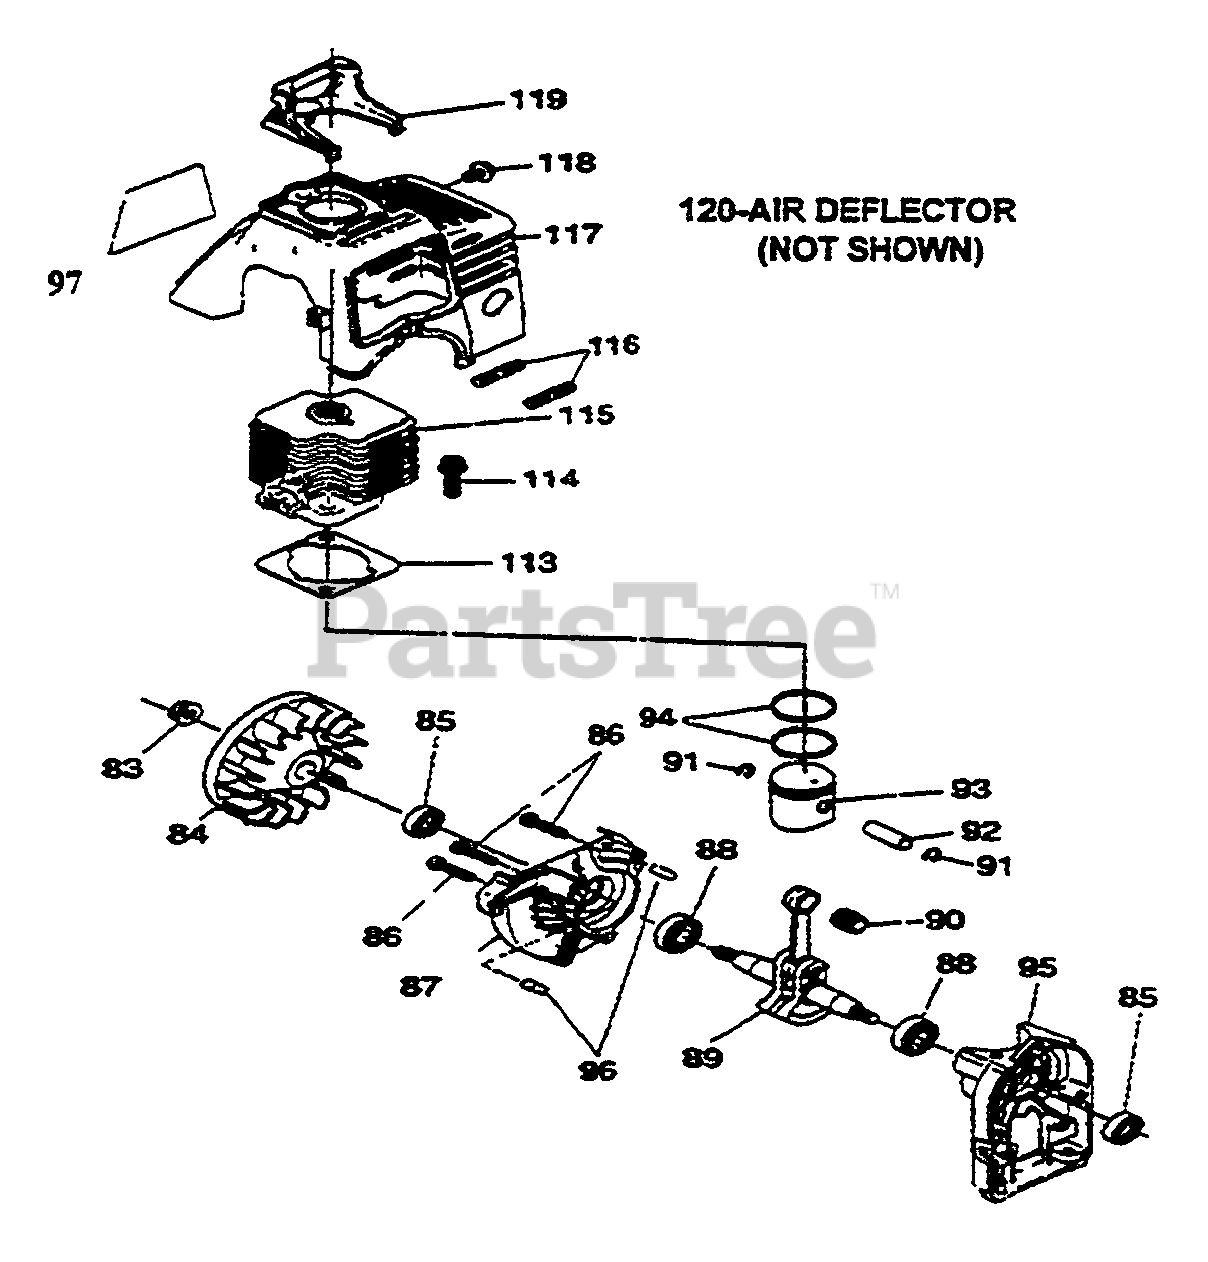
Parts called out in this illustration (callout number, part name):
83	NUT, CONICAL SPG.
85	OIL SEAL
87	CASE, DRIVE
88	BEARING, BALL
89	CRANKSHAFT ASSY
90	BEARING, NEEDLE
91	CLIP, PISTON PIN
92	PIN, PISTON
94	RING, TOP
95	CASE, STARTER
96	DOWEL PIN
97	DECAL
113	GASKET, CYLINDER
114	BOLT, FLANGE
116	BOLT, STUD
117	COVER, TOP
118	SCREW & WASHER
119	GUARD, SPARK PLUG
